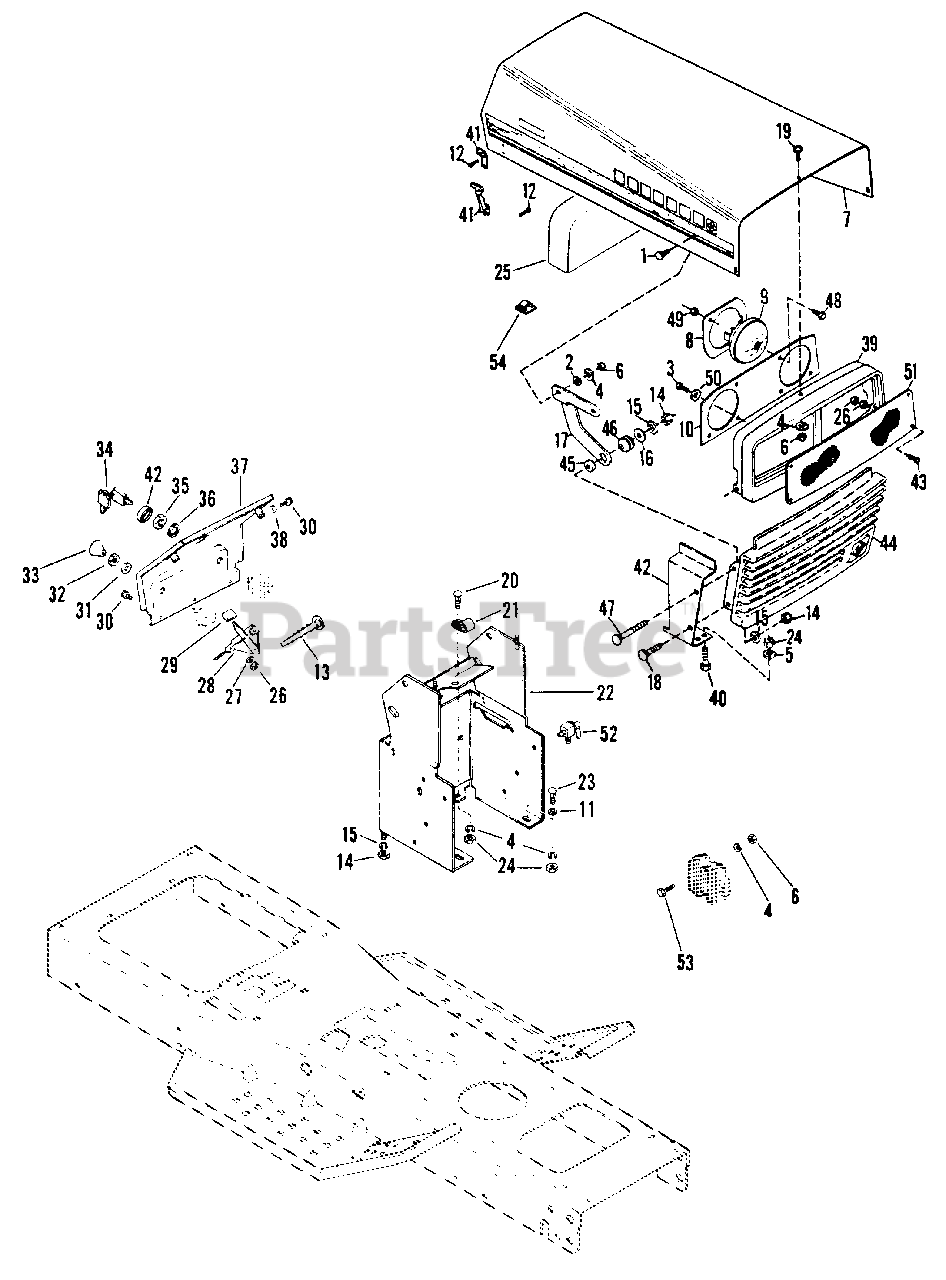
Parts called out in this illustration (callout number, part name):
1	BOLT, 1/4-20X.75 RD HD SQ NK
2	WASHER, FLAT .281X.625X.065
3	SCREW, TAPPING 1/4-20X.625
4	WASHER, LOCK 1/4 REG.
5	WASHER, LOCK 5/16 SP
6	NUT, HEX 1/4-20
7	HOOD
8	RING, HEADLIGHT RETAINER
9	HEADLIGHT
10	PANEL, HEADLIGHT REFLECTOR
11	WASHER, FLAT.312X.734X.065
12	RIVET, POP DOMED 1/8X.294
13	TIE DOWN
14	NUT, HEX 3/8-16
15	WASHER, LOCK 3/8 REG.
16	WASHER, FLAT .438X1.00X.083
17	HINGE, HOOD L.H.
17	HINGE, HOOD R.H.
18	BOLT, 3/8-16X1.00 RD HD SQ NK
19	SCREW, 1/4-20X.75
20	BOLT, HEX 5/16-18X.75
21	CLIP
22	BASE, DASH
23	BOLT, CARRIAGE 5/16-18X.75
24	NUT, HEX 5/16-18
25	BAFFLE, HOOD
26	NUT, 10-24 HEX
27	WASHER, LOCK NO. 10 SP.
28	CONTROL, THROTTLE
29	KNOB
30	SCREW, TAPPING 10-16X.375
31	WASHER
32	NUT, HEX 1/2-20
33	KNOB
34	KEY, IGNITION SWITCH
35	NUT, JAM 9/16-24
36	WASHER, LOCK 9/16 INT. TOOTH
37	DASH
38	WASHER, FLAT .250X.500X.049
39	BEZEL, HEADLIGHT
40	BOLT, HEX 5/16-18X.625
41	LATCH, FLEXIBLE
42	PANEL, SIDE R.H.
42	PANEL, SIDE L.H.
43	SCREW, MACHINE 10-24X.75 PHD
44	CASTING, GRILLE
45	SPACER
46	GROMMET
47	BOLT, 3/8-16X2.00 RD HD SQ NK
48	BOLT, HEX 1/4-20X1.25
49	NUT, LOCK 1/4-20
50	WASHER, LOCK 1/4 EXT. TH TYA
51	PANEL, HEADLIGHT LENSE
52	VALVE, BALL
53	BOLT, HEX 1/4-20X1.00
54	CLIP, WIRE
NS	SCREW, MACHINE 10-24X.75 PHD
NS	WASHR, FLAT .656X1.312X.095
NS	DECAL, GRAVELY LOGO
NS	DECAL, MODEL 1232-G
NS	DECAL, MODEL 1238-G
NS	DECAL, TRACTOR
NS	DECAL, SIDE STRIPE
NS	DECAL, MODEL 1238-H
NS	DECAL, MODEL 1232-H
NS	DECAL, OPERATING
NS	DECAL, FUEL VALVE
